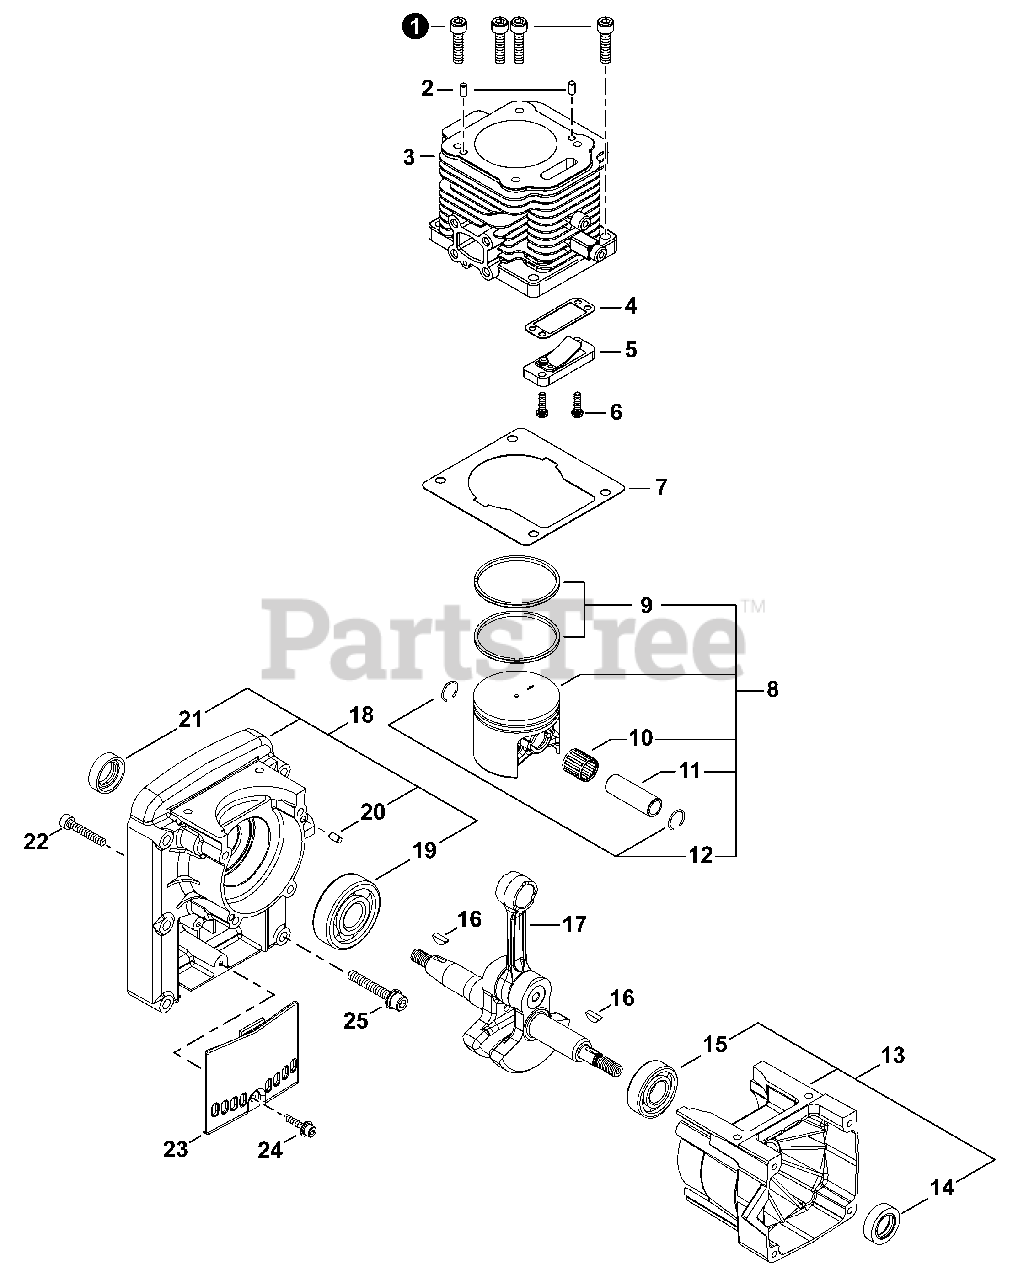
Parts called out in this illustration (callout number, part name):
1	BOLT 6×25
2	PIN, LOCATING 4×8
3	CYLINDER
4	GASKET, REED VALVE
5	VALVE ASSY, REED
6	SCREW M4×14
7	GASKET, CYLINDER
8	PISTON KIT
9	RING, PISTON
10	BEARING, NEEDLE 12
11	PIN, PISTON 12
12	RING, SNAP
13	CRANKCASE ASSY, S
14	SEAL, OIL 21
15	BEARING, BALL 6202 C3
16	KEY, WOODRUFF 3×10
17	CRANKSHAFT
18	CRANKCASE ASSY, M
19	BEARING, BALL 6303 C3
20	PIN, LOCATING 4×8
21	SEAL, OIL 21
22	BOLT 5×30
23	COVER, DUST
24	BOLT 4×20
25	BOLT, ADHESIVE M6×40
